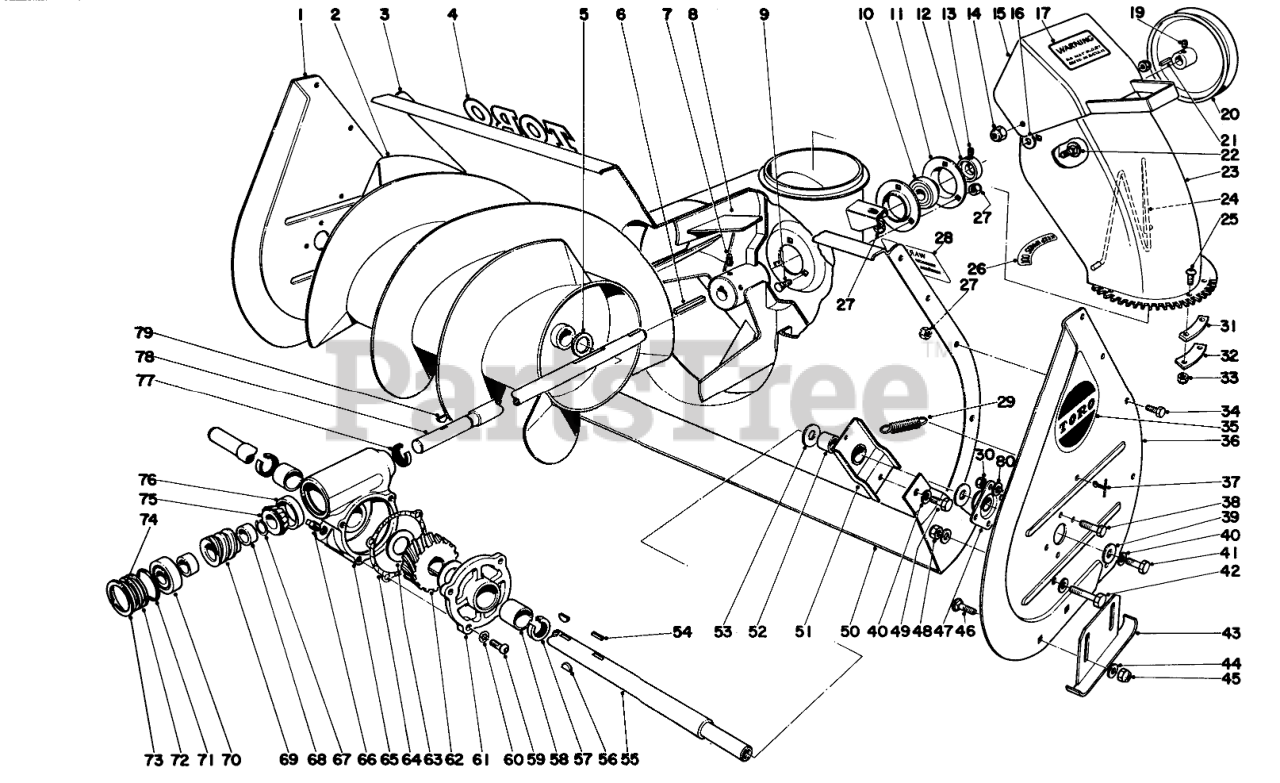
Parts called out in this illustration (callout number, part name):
1	Side Plate
2	Auger, R.H.
3	Auger Housing
4	Decal, Model 31727
5	Spacer
7	SCREW-SET, SQH
8	Impeller
9	BOLT-CARR
10	BALL BRG W/COLLAR
11	BRG FLANGE
12	EXT LOCKING COLLAR
13	SCREW-HSH
14	NUT-LOCK, NI
15	Deflector
16	WASHER-FLAT
17	Decal
19	SCREW-SET, SQH
20	1/2 X 9.5 DIA PULLEY
21	SQUARE KEY
22	SCREW-CARR
23	Upper Chute
24	Chute Wire
25	SCREW-HSBH
26	Decal
27	Nut
28	Decal
29	SPRING-TENSION
30	NUT-LOCK
31	CHUTE TAB SPACER
32	UPPER CHUTE TAB
33	Nut
34	SCREW-HH
35	Decal, Auger Sideplate
36	Side Plate L. H.
37	Retainer Spring
38	SCREW-HH
39	WASHER
40	WASHER-LOCK
41	SCREW-HH
42	SCREW-HH
43	Skid
44	WASHER-FLAT
45	NUT-LOCK, NI
46	BOLT-CARR
47	Bearing Flange
48	NUT-HEX
49	SCREW-HH
50	Scraper Blade
51	Scraper Blade Mount (Incl.Ref. No. 52)
52	BUSHING
53	WASHER-THRUST
55	Auger Shaft
56	Key, Early Production
57	SEAL-OIL
58	Bushing
59	SCREW-HSBH
60	WASHER-LOCK
61	Cover, Gear Box (Incl. Ref. No. 58)
62	GEAR-WORM, 27T
63	WASHER-THRUST
64	Gasket
65	Gear Box, Auger (Incl. Ref. Nos. 58 & 761)
66	PLUG-PIPE, SQH
67	RETAINER RING
68	Spacer
70	.750 BALL BEARING
71	O-RING
73	INTRNL RETAINING RING
75	3/4 ROLLER BRG CONE
76	1.750 ROLLER BRG CUP
77	SEAL-OIL
78	Shaft Worm
79	KEY-WOODRUFF
80	WASHER-FLAT
